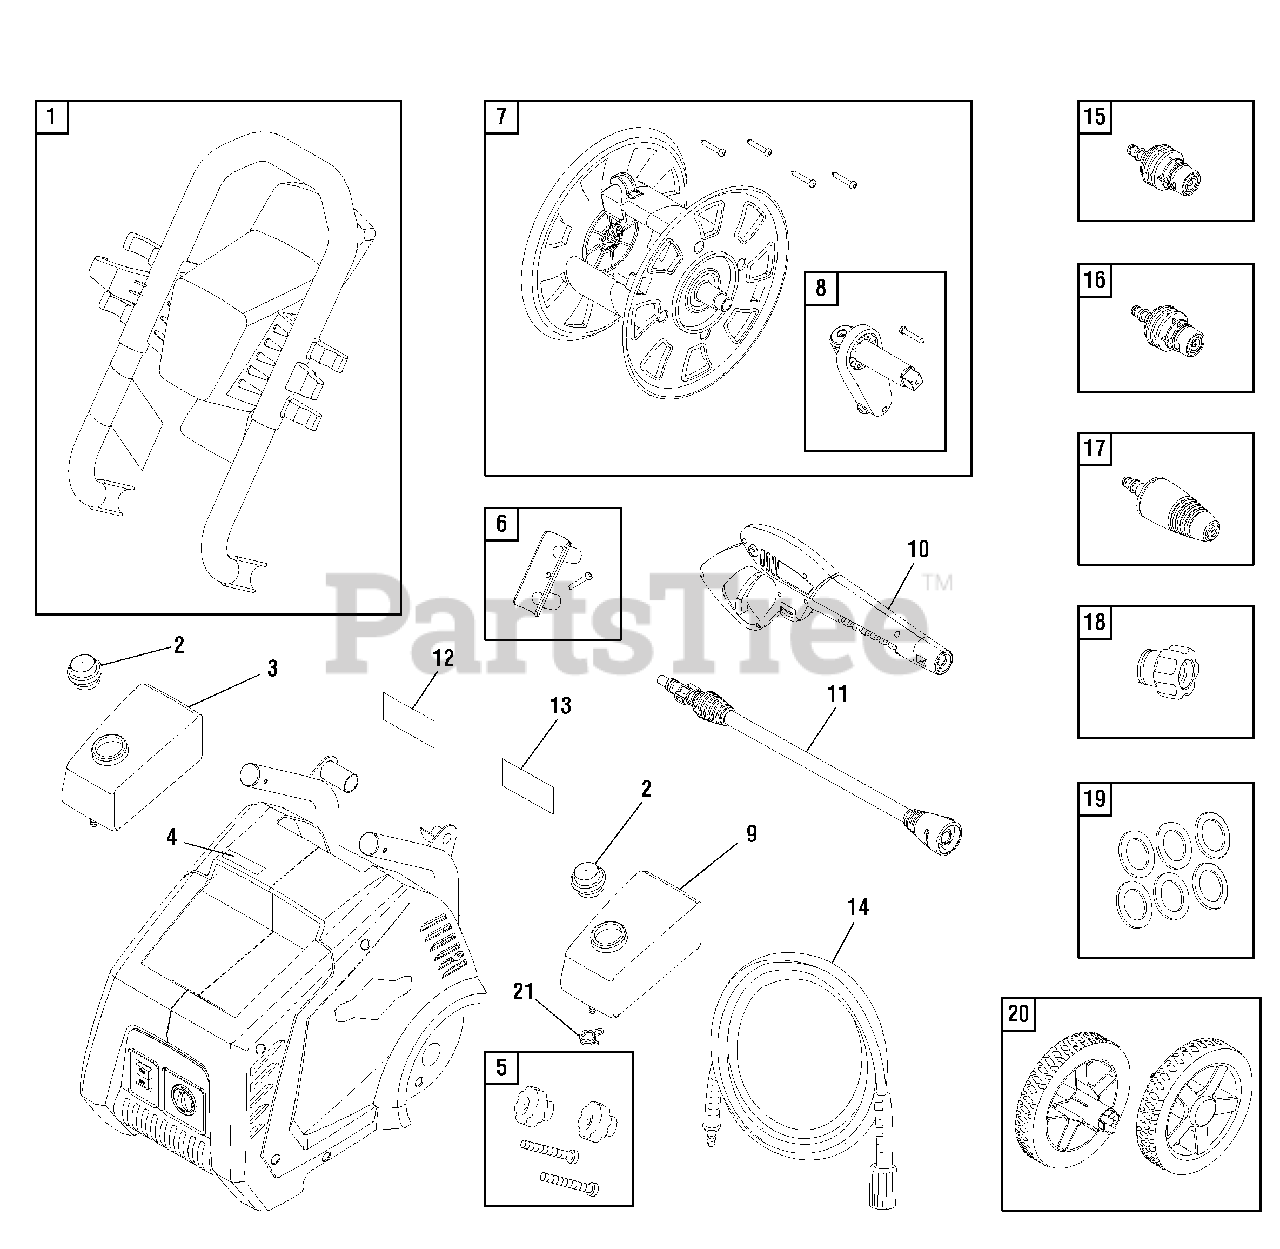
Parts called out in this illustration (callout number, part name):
3	TANK-LEFT SIDE
5	HANDLE-HARDWARE
7	KIT-HOSE REEL
8	HANDLE-HOSE REEL
9	TANK-RIGHT SIDE
